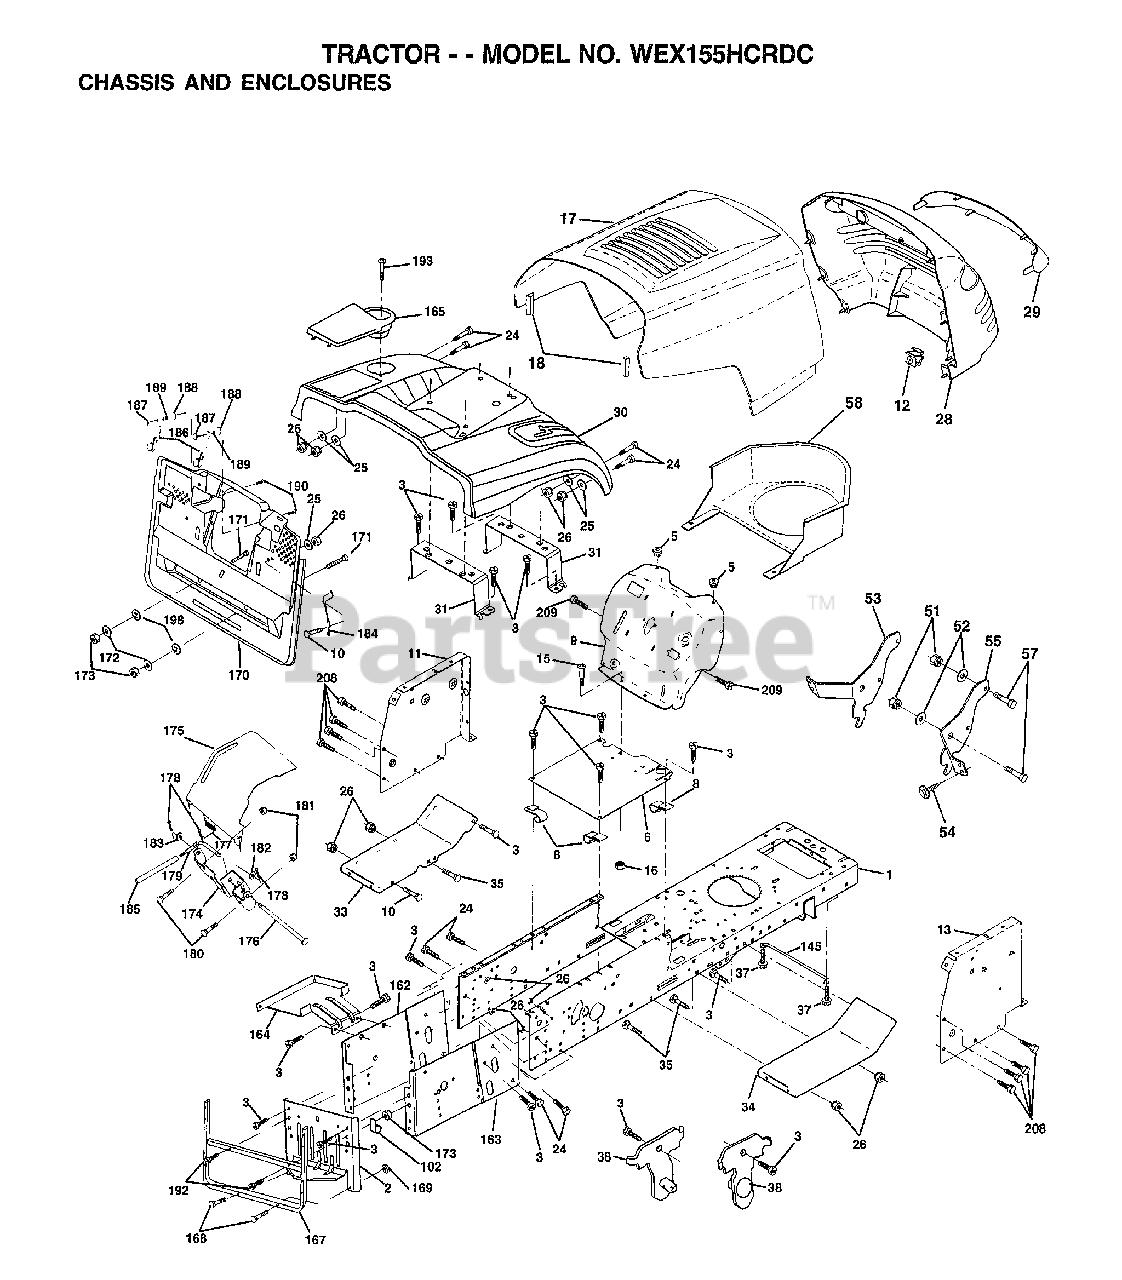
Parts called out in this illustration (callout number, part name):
2	DRAWBAR.CRD
3	SCREW
5	BUMPER-HOOD/DASH
6	SADDLE
8	"CLIP,INSULATOR"
9	DASH
11	"PANEL-DASH,LH"
12	CLIP.TINNERMAN
15	SCREW
17	HOOD.STEEL.ASSY
24	BOLT
25	WASHER
26	NUT
28	GRILLE-MS428
29	LENS.GRILLE.PRIVATE LABEL
30	FENDER.CRD.GREEN
31	BRKT.SUPT.FENDER.CRD
33	FOOTREST.LH.LT/GT
34	FOOTREST.RH.LT/GT
35	BOLT
37	SCREW LT
38	BRKT ASM PIVOT MOWER REAR
51	NUT
52	WASHER
53	BRACKET.GRILLE.LH
54	SCREW.HEX.WS.HD
55	BRACKET.GRILLE.RH
58	AIR DUCT
102	CLIP T
145	"ROD POVOT,CHASSIS"
162	BRKT.EXT.CHASSIS.LH.CRD
163	BRKT.EXT.CHASSIS.RH.CRD
164	SUPPORT.BATTERY.CRD
165	COVER.BATTERY.CRD.BLACK.LT
167	SUPT.ASM.BACKPLATE
168	BOLT-RD HD SQ NK
170	COVER.BACKPLATE.BLACK
171	BOLT.HEX.3/8-16X2-1/2
173	NUT
174	BRKT.SWITCH.FBI.CRD
175	GRUARD.DOOR.REAR.CRD
176	HINGE PIN
177	SPRING.COVER.LH
179	ROD.PIVOT.FBI.CRD
182	WASHER.385X.625
183	WASHER
184	BRKT.ACTUATOR.BAG.CRD
185	TUBE.LEVER.SWCH.FBI.CRD
186	LATCH ASSY.BAGGER
187	WELDNUT
188	WASHER #10
189	LOCKWASHER
190	SCREW
192	SCREW LT
193	SCREW
194	SCREW
198	NUT PUSH
208	SCREW
209	SCREW
